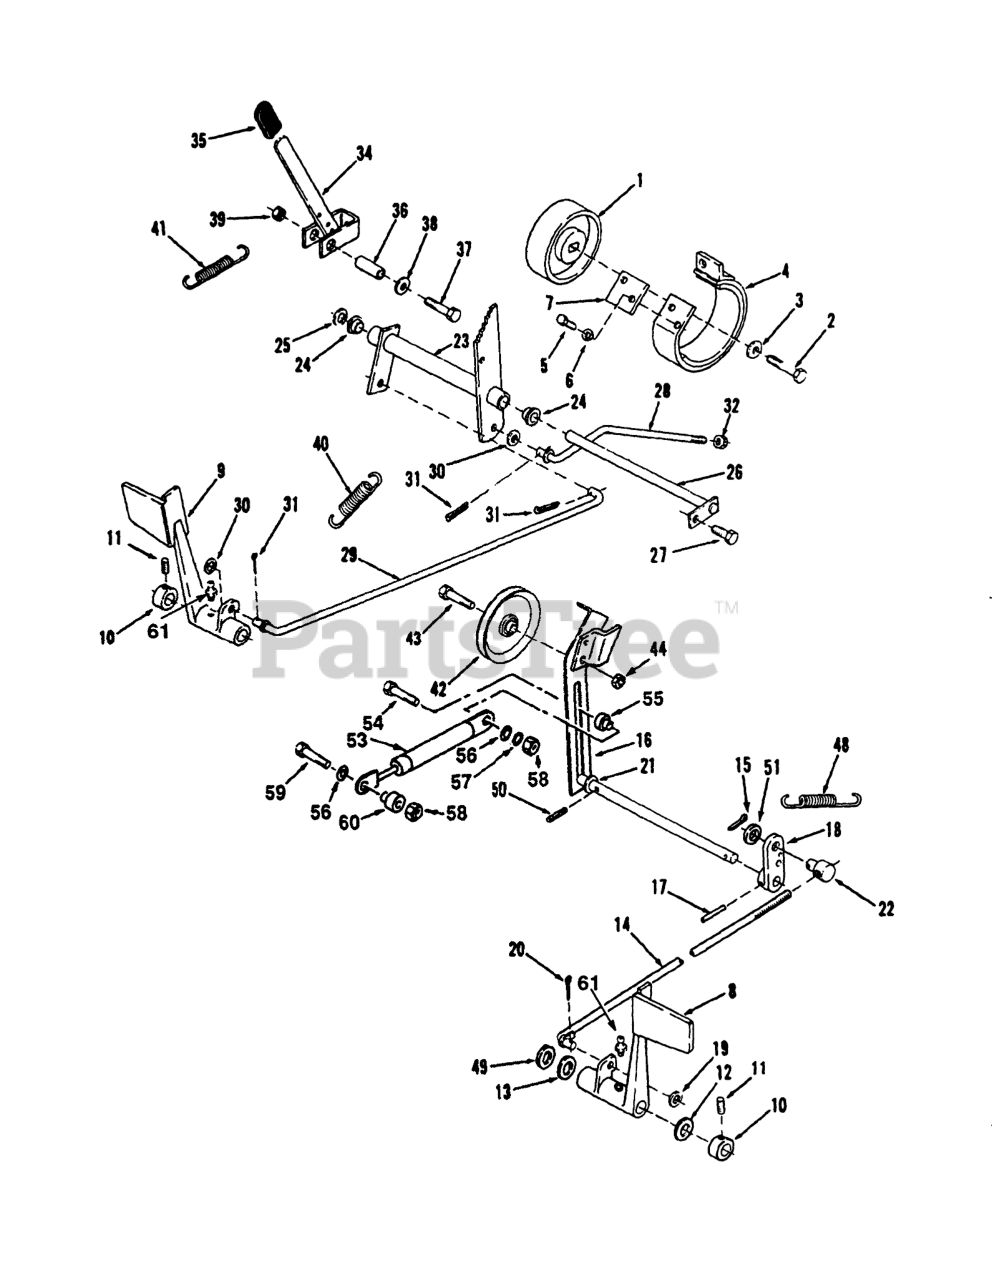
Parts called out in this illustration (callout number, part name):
1	DRUM-BRAKE
2	SCREW-HEX HD CAP
3	WASHER
4	BRAKE BAND ASM
5	SCREW-HH
6	WASHER-LOCK
7	Plate-Stop
8	PEDAL-CLUTCH R
9	Pedal-Brake
10	Collar
11	SCREW-HSH
12	WASHER-BOWED
13	WASHER
14	ROD AND GUIDE ASM
15	PIN-COTTER
16	Arm-Clutch Idler
17	PIN-SPIROL
18	Arm-Clutch Rod
19	WASHER-NYLON
20	PIN-COTTER
21	SHIM-WASHER
22	TRUNNION
23	Bellcrank Assy
24	BUSHING-FLANGED
25	WASHER-FLAT
26	ROD ASM
27	SCREW
28	ROD-REAR BRAKE
30	WASHER-NYLON
31	PIN-COTTER
32	NUT-LOCK, NI
34	ASSY-BRAKE LEVER WAB
35	GRIP
36	SPACER
37	SCREW-HH
38	WASHER-FLAT
39	LOCKNUT-FLANGE
40	SPRING-BRAKE
41	SPRING-EXTENSION
42	PULLEY-IDLER
43	BOLT-SPECIAL HEX
44	NUT-LOCK, NI
48	SPRING-CLUTCH
49	Washer
50	PIN-SPIROL
51	WASHER-FLAT
52	BRKT-DAMPER B
53	ASS'Y-GAS SPRING
54	SCREW-HH
55	SPACER-SHOULDER-.200
56	WASHER-FLAT
57	WASHER-LOCK
58	NUT-LOCK, NI
59	SCREW-HH
60	SPACER-SHOULDER-.400
61	FITTING-GREASE
